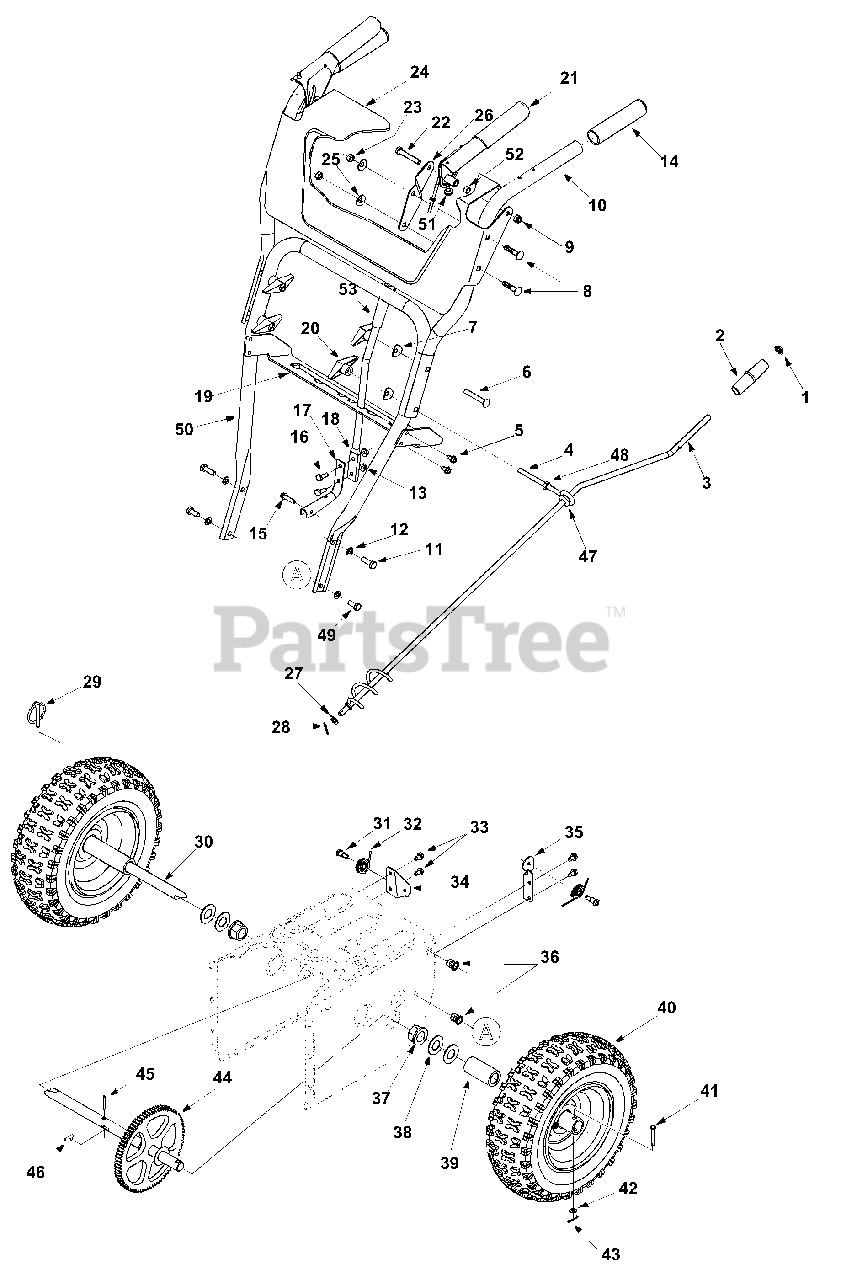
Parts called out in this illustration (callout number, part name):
1	Push Cap
2	Chute Crank Knob
3	Chute Crank Assembly
4	Eye Bolt
5	TT Screw 1/4-20 x 0.5"
6	Carriage Screw 5/16-18 x 2.25"
7	Saddle Washer
8	Carriage Bolt
9	Hex Lock Nut 5/16-18
12	Lock Washer 5/16
13	Flange Lock Nut 1/4-20
14	Handle Grip
15	TT Screw 1/4-20 x 1.0"
16	Hex Bolt 1/4-20 x 0.75"
17	Shift Arm
20	Handle Knob
21	Clutch Lever LH
22	Hex Bolt 5/16-18 x 2.0"
23	Hex Lock Patch Nut 5/16-18
28	Hairpin Clip
29	Klik Pin
30	Axle: 13"
31	C Screw 1/4-28 x 0.375"
32	Cable Roller
33	TT Screw 1/4-20 x 0.5"
37	Hex Flange Bearing
38	Flat Washer
39	Spacer
41	Clevis Pin
42	Flat Washer
43	Cotter Pin
44	Gear 80T
45	Roll Pin
46	Key: Hi Pro
47	Rubber Grommet
48	Hex Nut 5/16-18
49	Hex Bolt 5/16-18 x 0.75"
51	Rubber Bumper
52	Spacer
53	Shift Lever Grip
